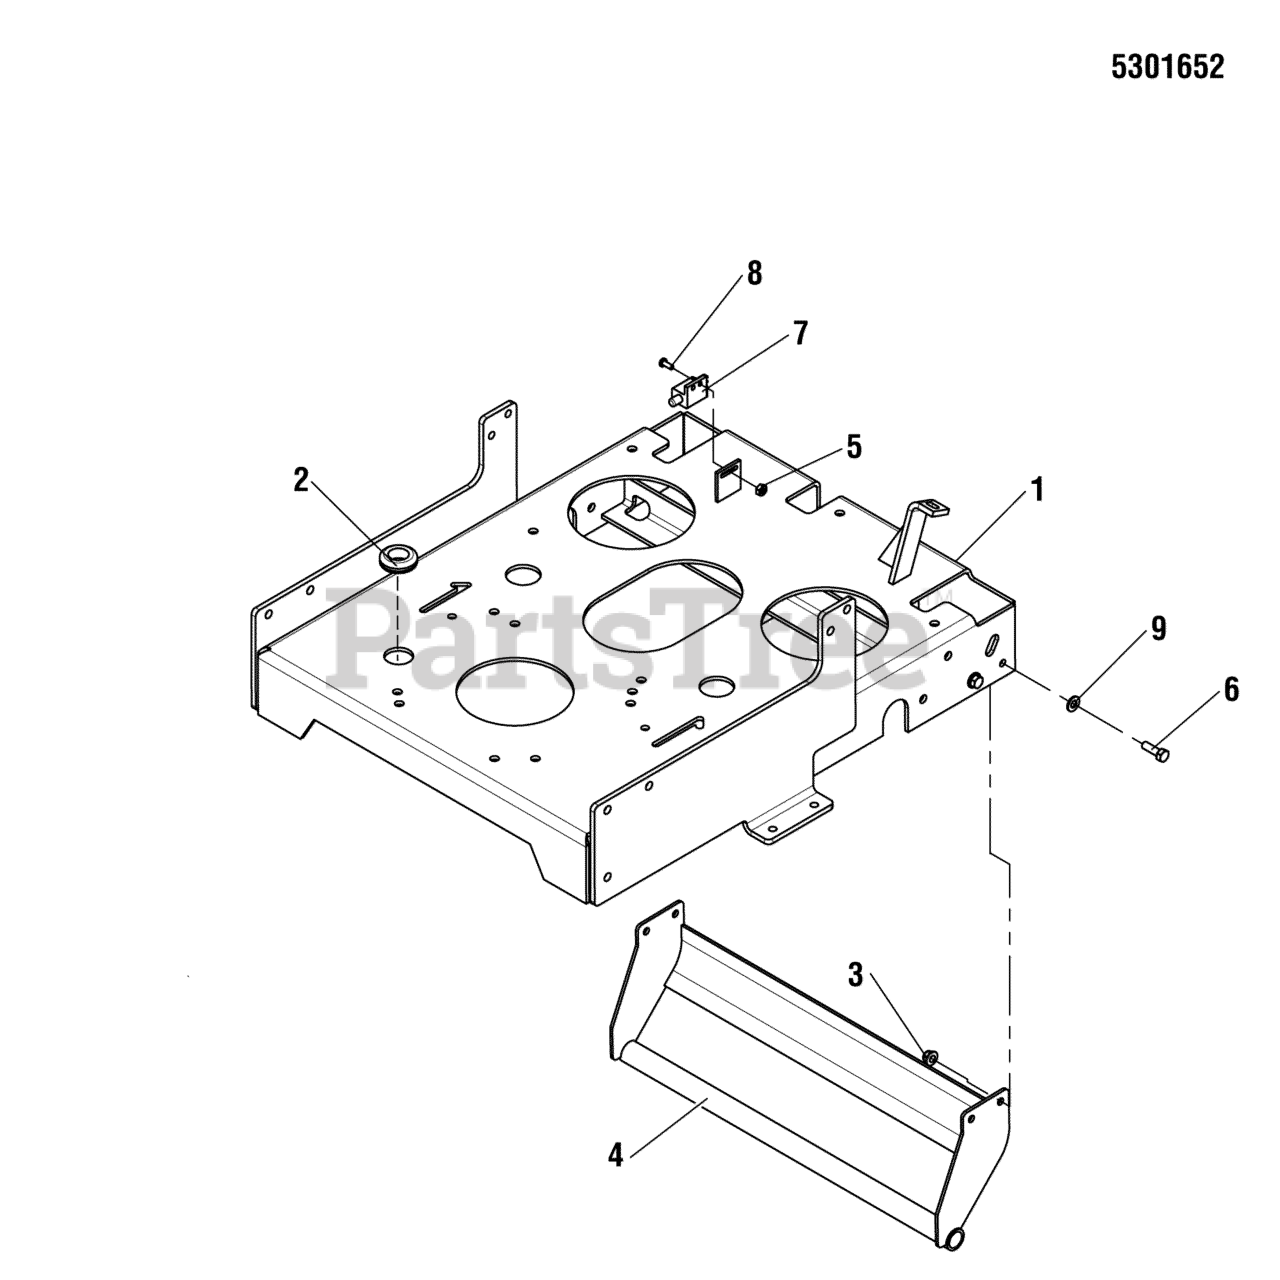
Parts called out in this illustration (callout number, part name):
1	WELD, ENGINE DECK, SNP PRO WB - RED
2	GROMMET, 7/8
3	NUT, 5/16-18 HEX NYLOCK FLANGE
4	WELD, BUMPER - SNP PRO DDS - RED
5	NUT, #10-24 HEX
6	BOLT, 5/16-18 X 1 GD5 YZ
7	SWITCH, PLUNGER, N.C.
8	SCREW, #10-24 X 1/2 ROUND PHILLIPS
9	WASHER, 5/16" SAE
